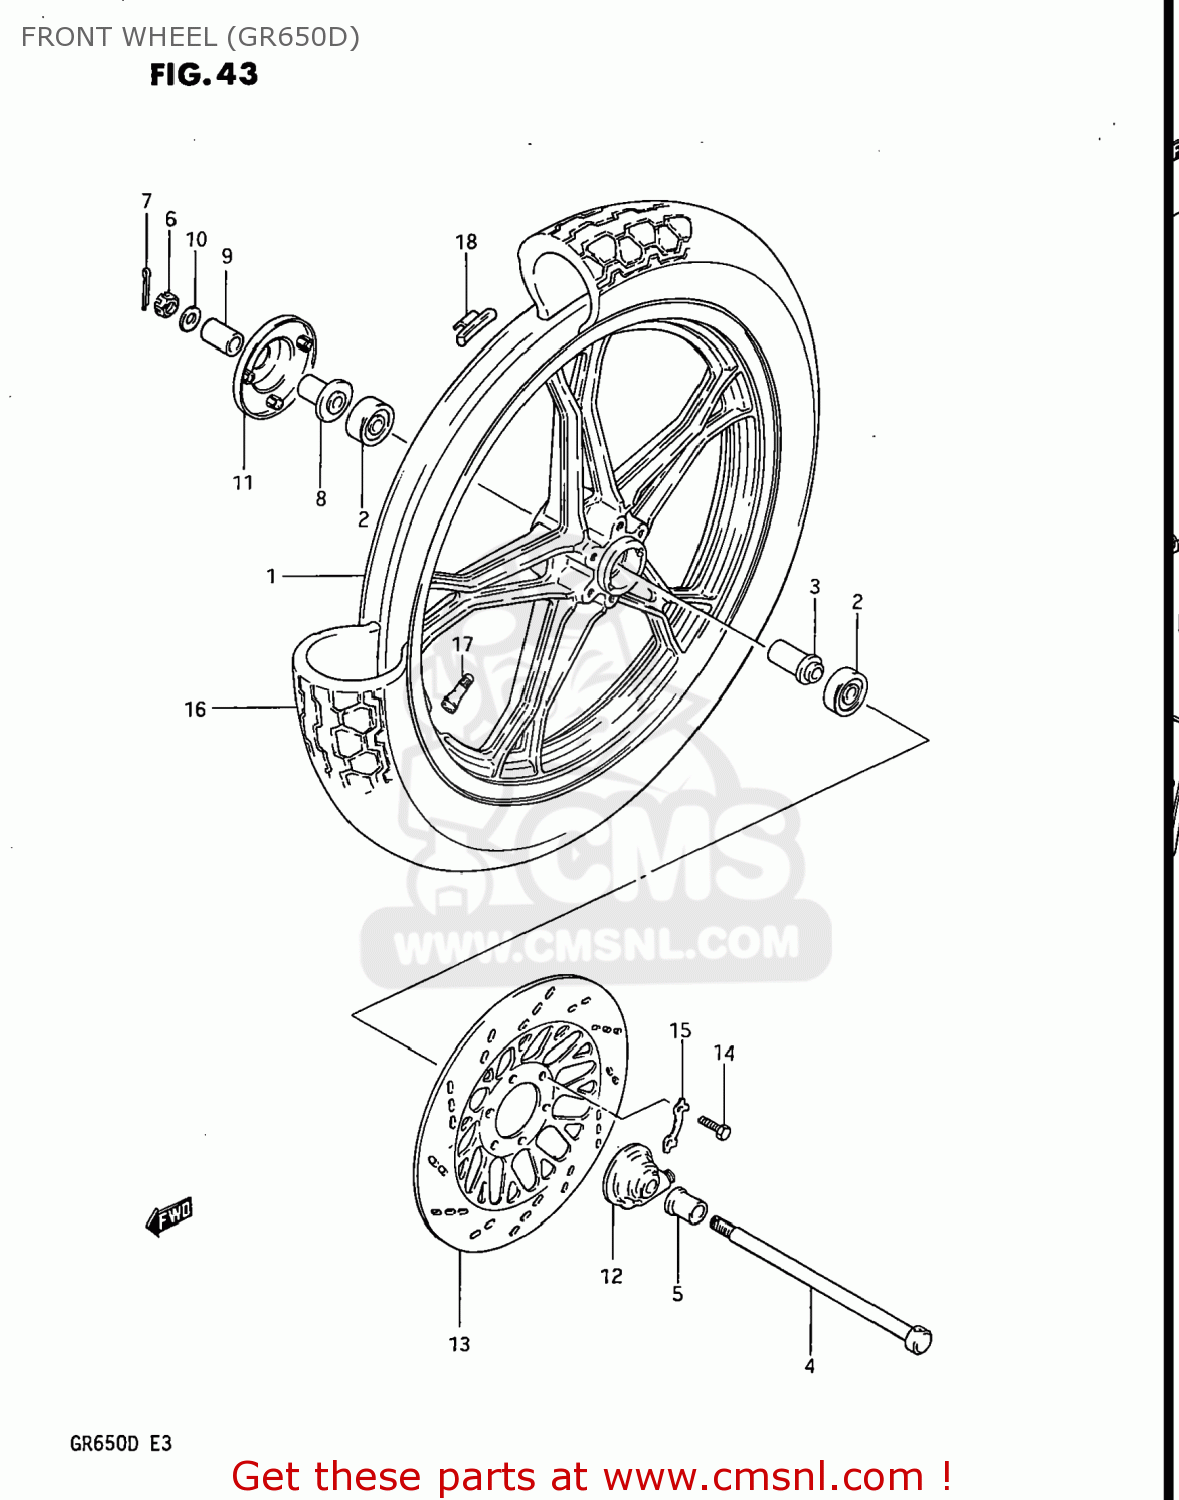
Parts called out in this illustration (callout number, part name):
1	CASTING WHEEL,FRONT 1.85
2	BEARING
3	SPACER,FR HUB BEARING
4	AXLE,FR
5	SPACER,FRONT AXLE,RIGHT
6	NUT 12MM
7	COTTER PIN
8	SPACER,FR AXLE,R
9	SPACER,FRONT AXLE,RIGHT
10	WASHER
11	COVER,FR HUB,R
12	BOX ASSY,SPEEDOMETER GEAR
13	DISC,FR BRAKE,L
14	BOLT(8X25)
15	WASHER
16	TIRE,FRONT
17	VALVE,TIRE
18	BALANCER,WHEEL
